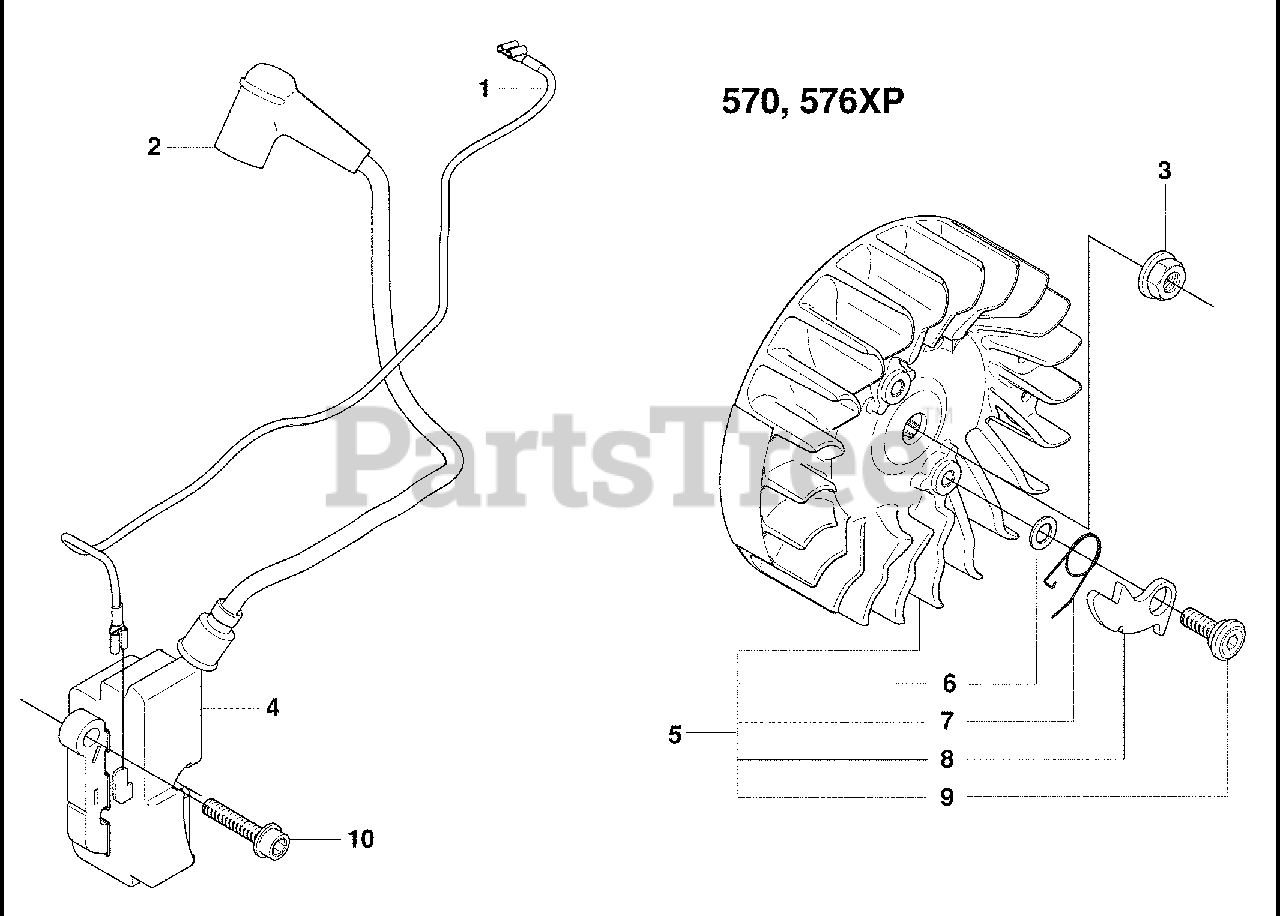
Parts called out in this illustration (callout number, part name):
1	Shorting Lead
2	Spark Plug Connection Kit
3	Nut with Washer
4	Ignition Module
9	Screw, M5 X 14
